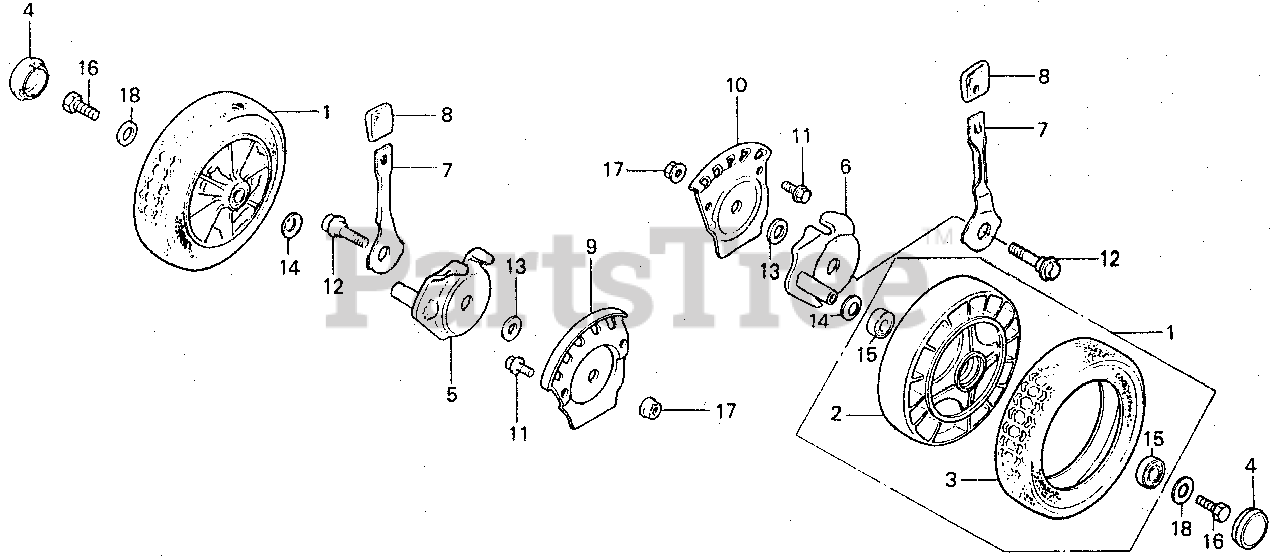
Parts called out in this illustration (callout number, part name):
1	WHEEL ASSY., FR. *NH31* (MCKINLEY WHITE) (NOT AVAILABLE)
1	WHEEL ASSY., FR. *NH31* (MCKINLEY WHITE)
2	HUB, FR. WHEEL *NH31* (MCKINLEY WHITE)
3	TIRE, FR. (7INCH)
4	CAP, WHEEL
5	ARM, R. FR. ADJUSTER
6	ARM, L. FR. ADJUSTER (NOT AVAILABLE)
7	PLATE, FR. ADJUSTING (NOT AVAILABLE)
8	GRIP, ADJUSTER
9	PANEL, R. FR. ADJUSTING
10	PANEL, L. FR. ADJUSTING
11	BOLT, FLANGE (6X12) (CT200)
12	BOLT, FR. ADJUSTER ARM (NOT AVAILABLE)
13	WASHER (10MM) (NOT AVAILABLE)
14	SPRING, LEVER
15	BEARING, RADIAL BALL
15	BEARING, RADIAL BALL (PA641-4)
16	BOLT, HEX. (8X12)
17	NUT, FLANGE (10MM)
18	WASHER, PLAIN (8MM)
